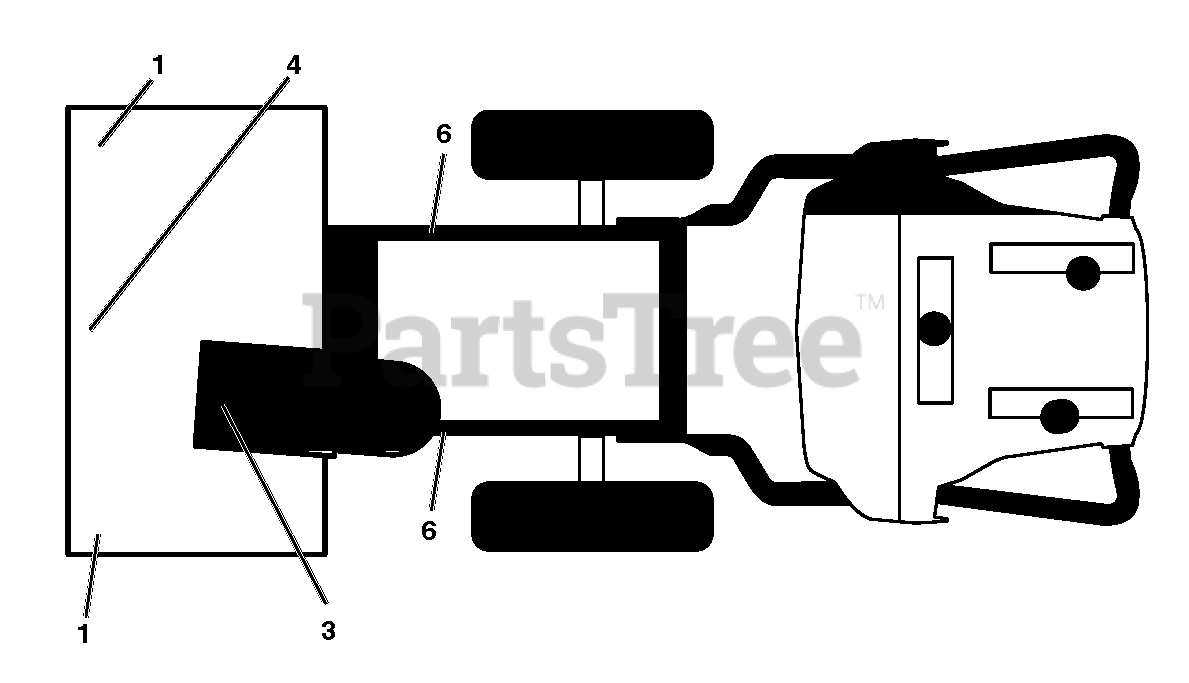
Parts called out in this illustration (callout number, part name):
1	DECAL.AUGER.SAFETY.EU/SC
3	DECAL.CHUTE.SAFETY.EU/SC
4	DECAL.AUGER."READ.OWN.MAN"EU/S
6	DECAL.BELT.GUARD.CAUT
